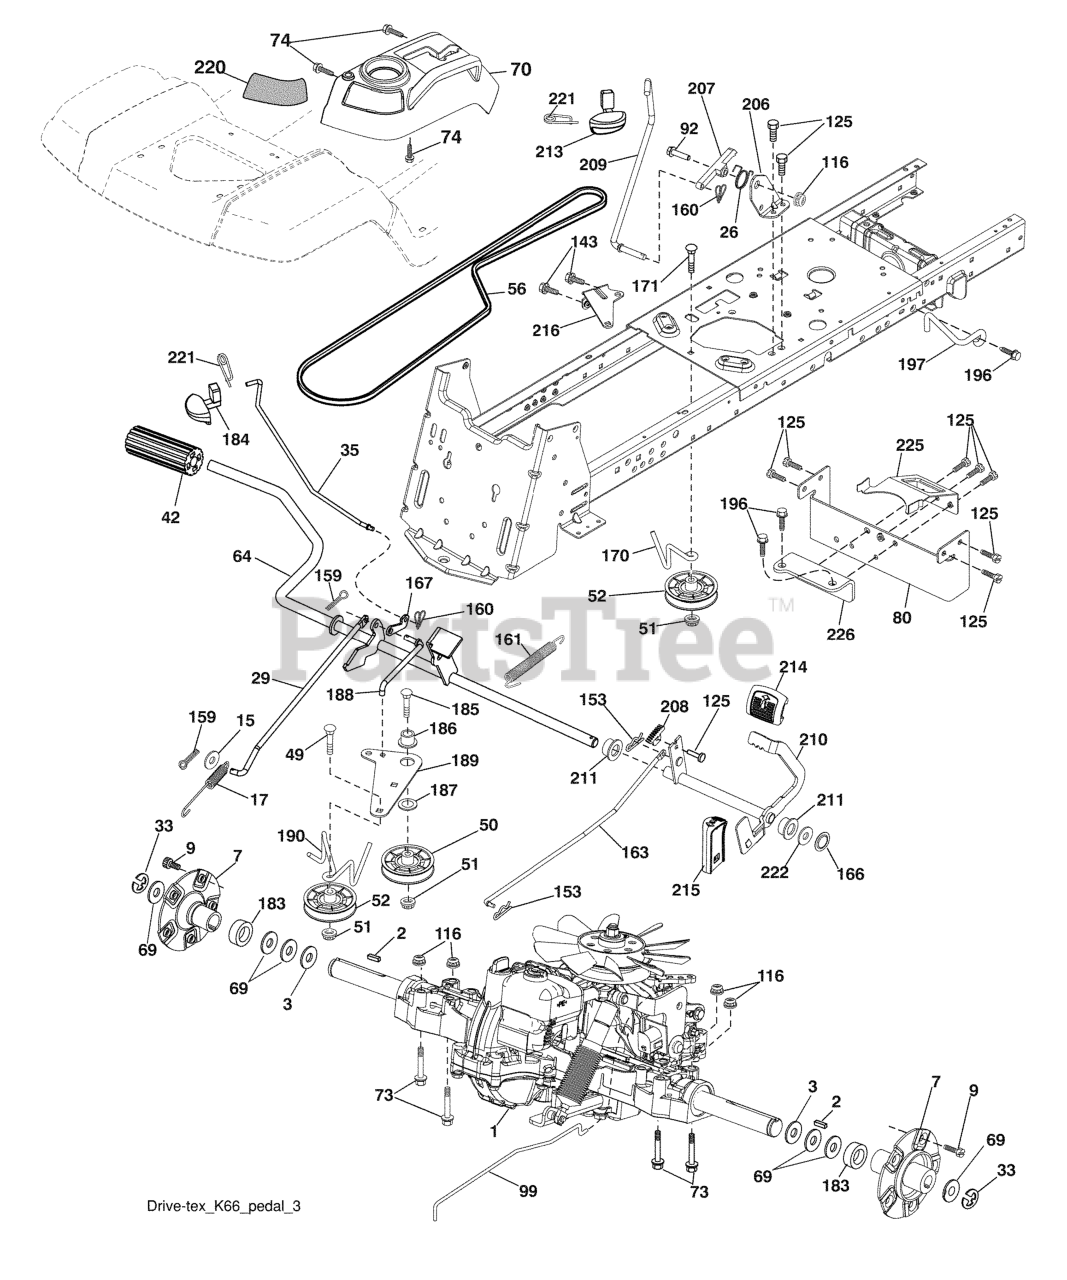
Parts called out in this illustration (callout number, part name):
1	TRANSAXLE.K66Y.PEDAL.CONTROL
2	KEY 1/4 X 2.5
7	HUB.ASM.WHEEL.REAR.23"TEX
9	HUB BOLT
15	WASHER
17	SPRING.BRAKE.K46
26	SPRING.RETURN.CRUISE
29	ROD.BRAKE.K66
33	E RING HYT
35	ROD.BRAKE.PARKING.GT.H
42	PEDAL COVER T
50	IDLER.FLAT.910.OFFSET
51	NUT LOCK FLG 3/8-16 UNC
52	IDLER.V-GROOVE.910.OFFSET
64	SHAFT.ASM.PEDAL.BRK.CNTR
70	RP CONSOLE.ASM.PCH.W/TB
73	BOLT HEX 5/16-18 GR 5
74	SCREW.HI-LO.CONSOLE
80	STRAP.TORQUE.K66
92	BOLT
99	ROD.SPRING.BYPASS.K66.GT.Z
116	NUT LOCK HEX FLANGE 5/16-18
125	SCREW
143	Screw 5/16-18 x 1/2
153	RETAINER M
159	COTTER PIN
160	RETAINER CLIP
161	SPRING, RETURN LT
163	ROD.PEDAL.CONTROL
166	NUT.PUSH.625.2006
167	LATCH.BRAKE.SPRING
170	KEEPER.V-IDLER.CENTER.
171	BOLT
183	SPACER.AXLE.HG.TEX
184	HANDLE.PARKG.BRK.HUSQ X667
186	SPACER.RETAINER
187	WASHER 12/32X2X10GA
188	RP.LINK.CLUTCH.GROUND.DRIVE
189	BELLCRANK.GROUND.DRIVE.TEX.
190	KEEPER.BELLCRANK.DRIVE
196	SCREW 3/8-16X1
197	BRKT.ANIT-ROTATION.CLUTCH
206	BRKT.MOUNT.LATCH.CRUIS
207	LATCH.CONTROL.CRUISE
208	GEAR.SECTOR.CONTROL.CR
209	ROD.CONTROL.CRUISE.GT.
210	ROCKER.ASM.PEDAL.CONTR
211	BEARING.NYLON
213	KNOB.CONTROL.CRUSIE.HU
214	PEDAL.FORWARD.HUSQVARNA.DEALER
215	PEDAL.REVERSE.TEX.GT.4
216	BRACKET.PULLEY.IDLER.W/TEX
220	REFLECTOR.RH.TEX GT
221	RETAINER.SPRING.CLIP.H
222	WASHER 21/32 X 1-1/4 X 10 GA.
225	KEEPER.BELT.TRANSAXLE.K66
226	BRACKET.MOUNT.TORQUE.K66.TG
